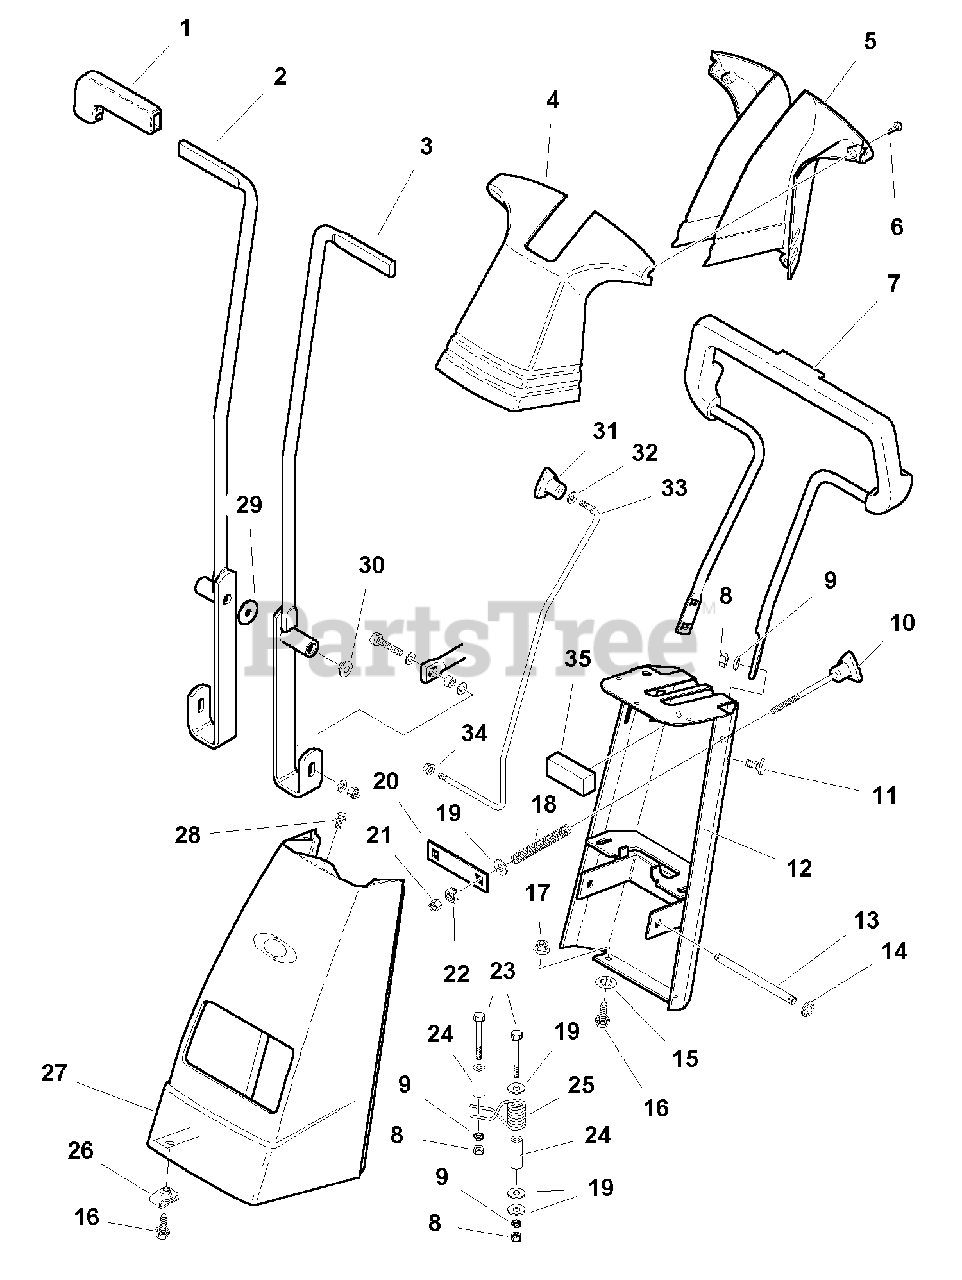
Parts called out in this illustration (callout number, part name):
1	GRIP, Control Handle
2	CONTROL LEVER ASSEMBLY, RH
3	CONTROL LEVER ASSEMBLY, LH
4	ENCLOSURE, Handrail, Front
5	ENCLOSURE, Handrail, Rear
6	CAPSCREW, Self Tapping #10-24 x 5/8
7	HANDRAIL ASSEMBLY
8	NUT, Hex, 5/16-18
9	LOCKWASHER, 5/16
10	KNOB, 5/16-18 x 4-3/8
11	CARRIAGE BOLT, 5/16-18 x 3/4
12	DASH SUPPORT ASSEMBLY
13	SHAFT, Control Handles
14	RING, "E" External #37
15	NUT, Push, 5/16
16	CAPSCREW, Hex, Whiz Lock, 5/16-18 x 3/4
17	NUT, Hex, Whiz Flange Lock, 5/16-18
19	WASHER, Plain, 5/16
21	NUT, Hex Lock ESNA 5/16-18
22	NUT, Retainer Speed 5/16-18
23	CAPSCREW, Hex Head, 5/16-18 x 2-1./2
25	SPRING, Torsion, RH
25	SPRING, Torsion, LH
26	NUT, Pal, 5/16-18
27	SHROUD, Front, With Headlight Assembly Included, Orange
27	SHROUD, Front, With Headlight Assembly Included, Red
27	SHROUD, Front (Without Headlight Cut Out)
27	SHROUD, Front (With Headlight Cut Out)
27	SHROUD, Front (Without Headlight Cut Out), Red
27	SHROUD, Front (With Headlight Cut Out), Red
28	CAPSCREW, Hex Washer. Head, Taptite, 1/4-20 x 1/2
32	WASHER, Plain 1/4
33	ROD, Parking Brake
34	NUT, Hex Flange Center Lock, 1/4
35	PAD, Neoprene
